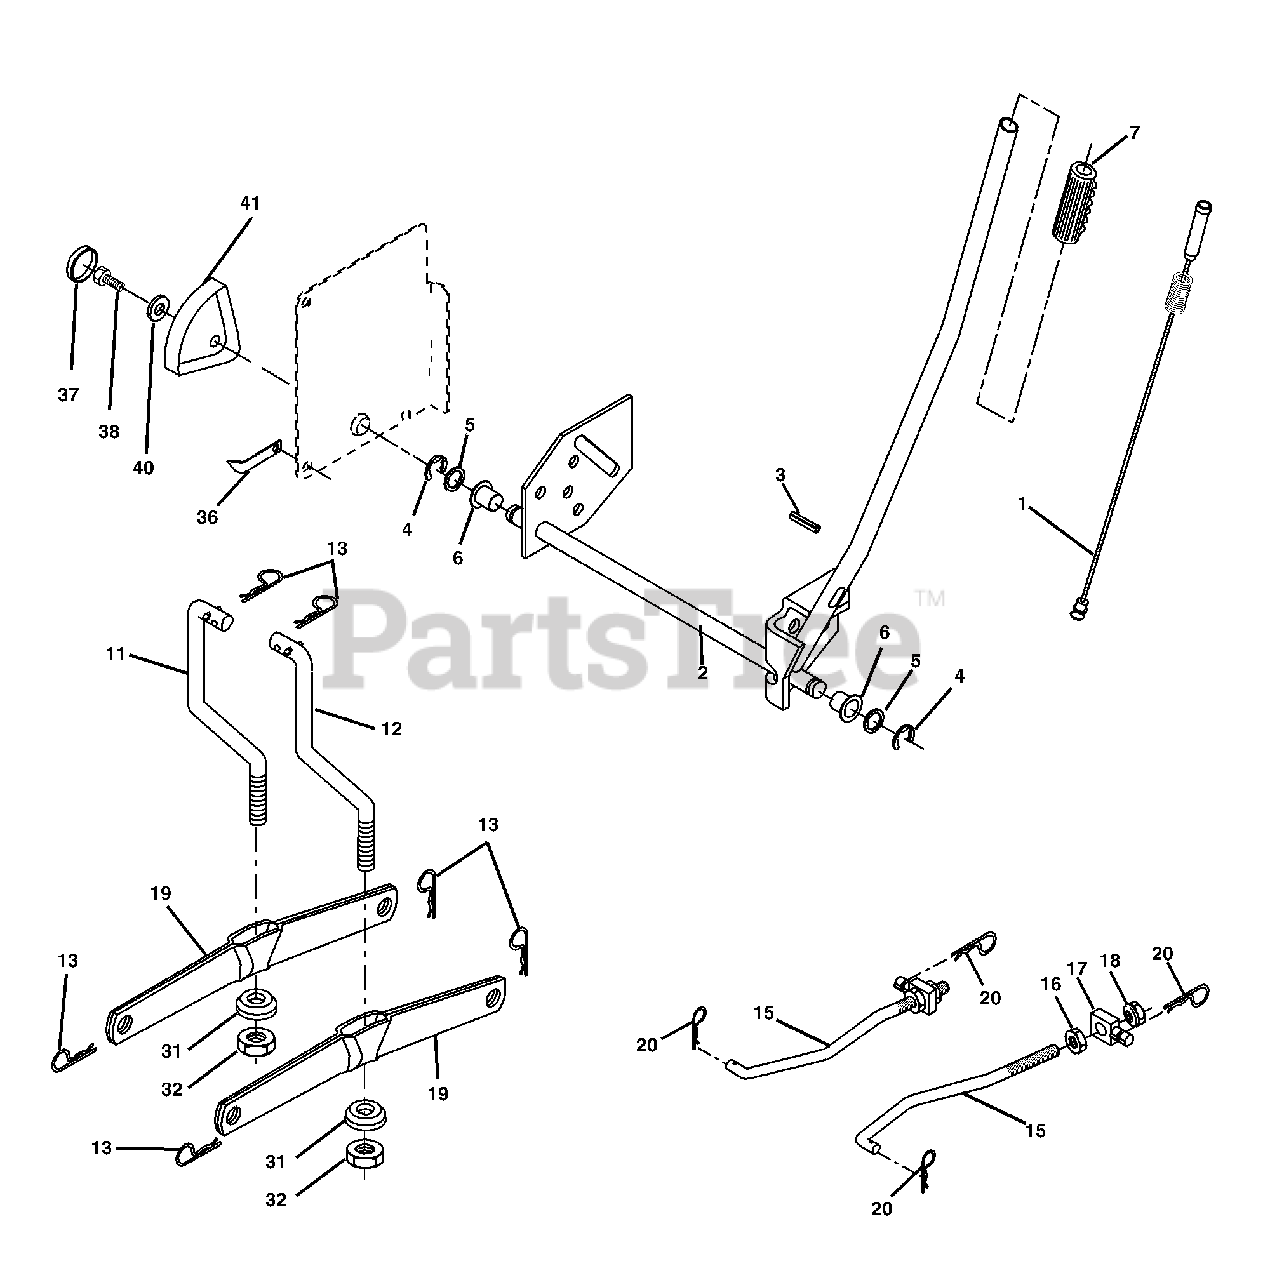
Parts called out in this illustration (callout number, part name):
1	Plunger Assembly
2	Shaft Assembly, Lift
3	Pin, Groove
5	Washer 21/32 x 1 x 21 Ga.
6	Bearing, Nylon
7	Grip, Handle, Fluted
11	Link, Lift, L.H.
12	Link, Lift, R.H.
13	Retainer Spring
15	Link Front Sus.
16	Nut Hex Jam 1/2-13 unc
17	Trunnion Front Susp.
18	Nut Lock w/Wsh 1/2-13 unc
19	Arm Asm. Suspension Mower
20	Retainer Spring
31	Bearing Pivot Lift
32	Nut Crownlock 3/8-24
36	Pointer Height Indicator
37	Plug Hole
38	Screw 5/16-18 x 1
40	Washer 11/32 x 1-1/2 x 10 Ga.
41	Indicator Height Stlt
